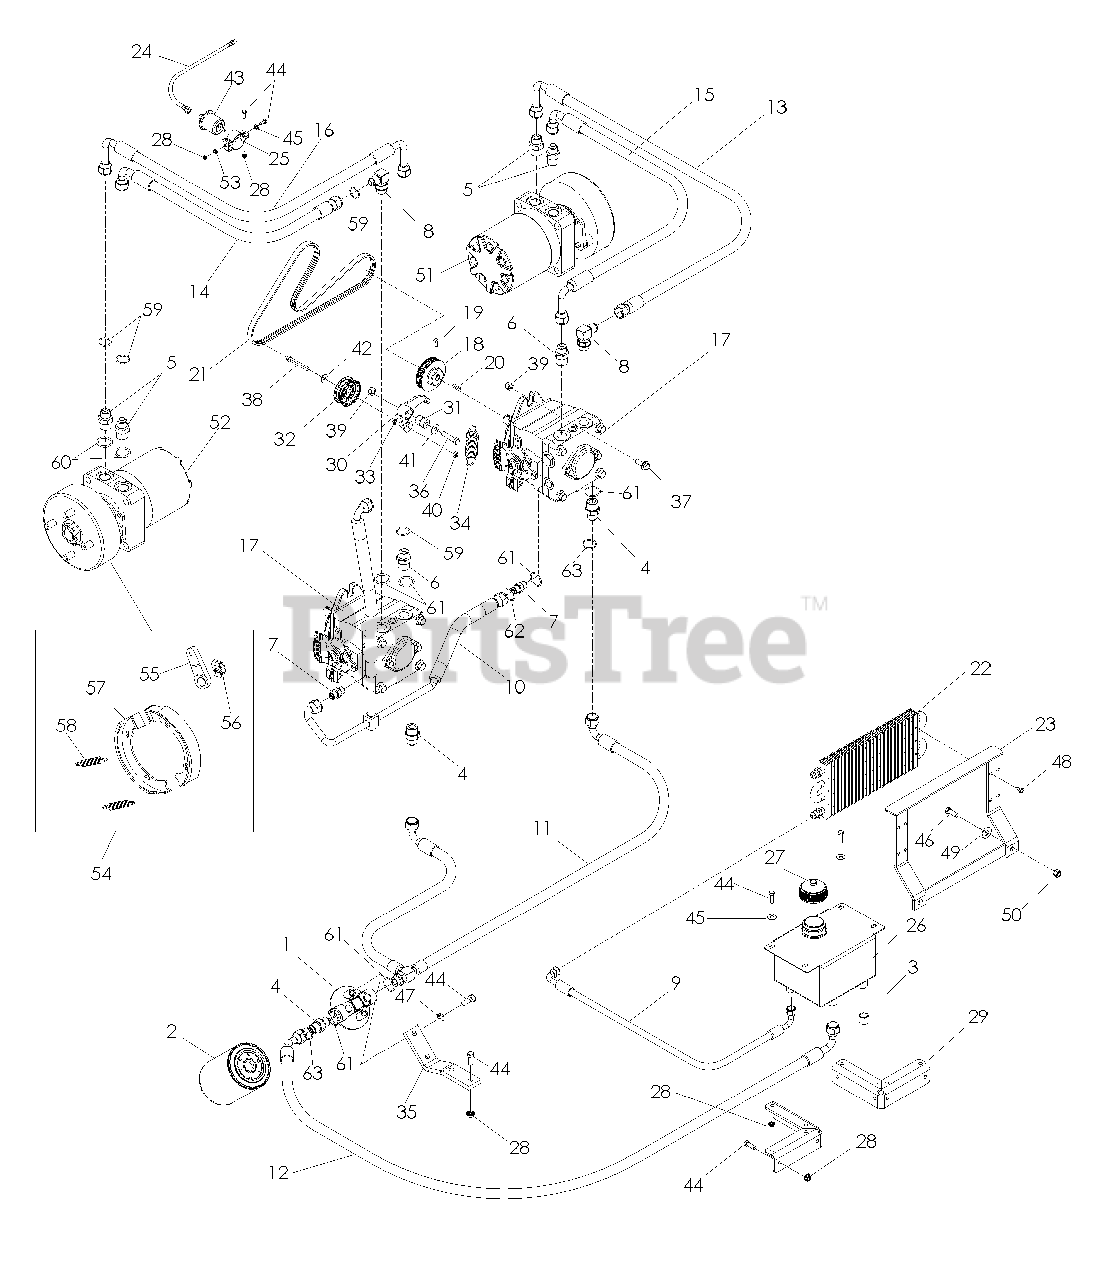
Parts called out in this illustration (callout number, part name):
1	FILTER HEAD
4	STRAIGHT CONNECTOR
18	SHEAVE, PUMP
19	SCREW 5/16-18 x 1
20	KEY 5mm SQ x 36mm
21	BELT, PUMP
23	MOUNT, COOLER
25	CLAMP, OIL SENDER
27	CAP, RESERVOIR
28	NUT 1/4-20 WHIZLK
32	PULLEY, IDLER
33	ZERK 90° 1/4-28
35	MOUNT, FILTER
36	HCS 1/2-13 x2 1/2
37	BOLT 1/2-13 x 1 1/4 WHIZLK
38	HCS 3/8-16 x3
39	NUT 1/2-13 HEX NYLOC
40	NUT 3/8-16 HEX NYLOC
41	WASHER 1/2 FLAT
42	WASHER 3/8 SAE FLT
43	SENDER, OIL PRESSURE
44	HCS 1/4-20 x 3/4
45	WASHER 1/4 FLAT
46	HCS 5/16-18 x 1
47	WASHER 1/4 SPLIT LOCK
48	SCREW 10-12 x 3/4 THD FRM
49	WASHER 5/16 STD FLT
50	NUT 5/16-18 HEX NYLOC
51	WHEEL MTR ASM, LT
52	WHEEL MTR ASM, RT
53	WASHER 1/4 EXTLK STAR
54	SHOE, COMPLETE W/BACKING PLATE
57	SHOE ASSEMBLY
58	RETURN SPRING
